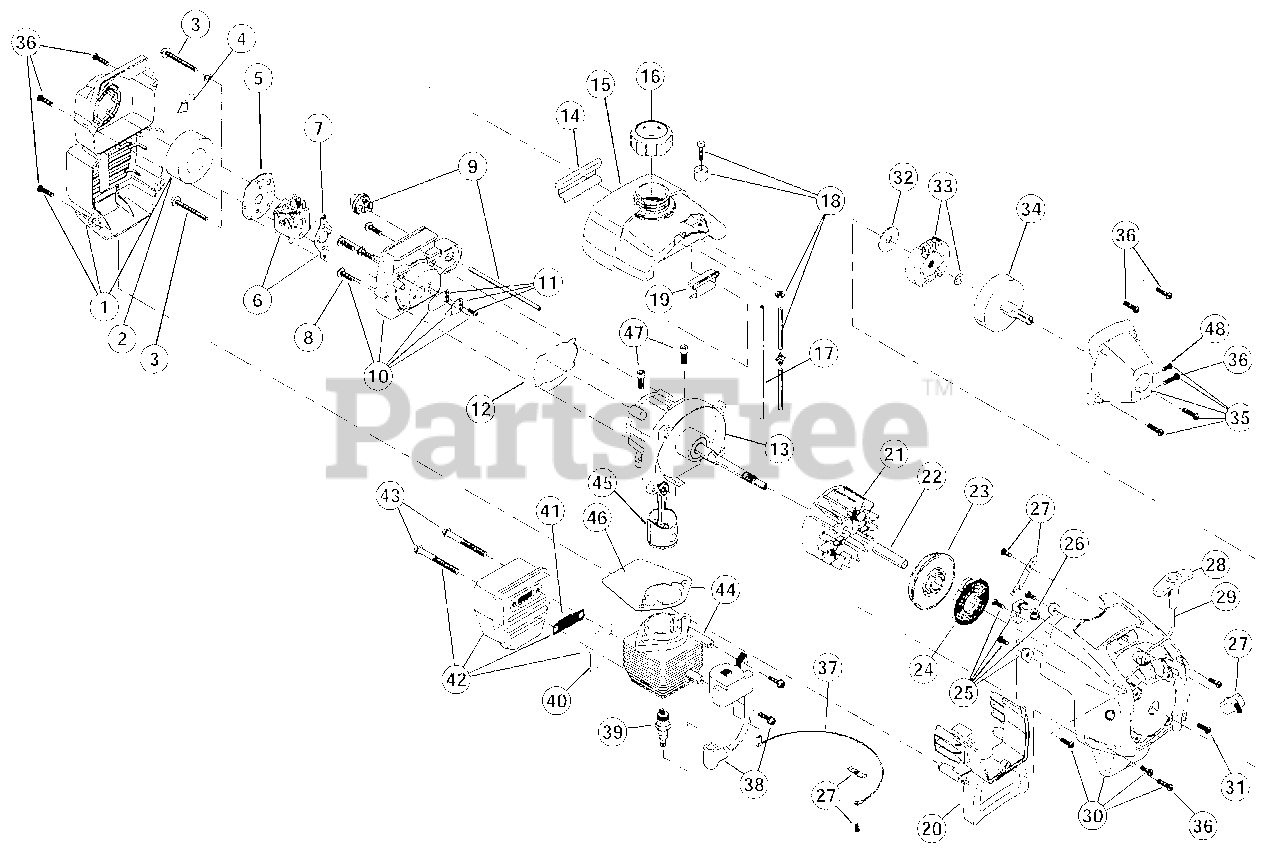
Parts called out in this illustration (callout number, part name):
1	Carburetor/Air Cleaner Cover Assembly
2	Air Cleaner Filter
3	Carburetor Mounting Screws
4	Choke Lever
5	Plate
6	Carburetor Assembly
7	Carburetor Gasket
8	Carb Mount Screw
9	Primer & Hose Assembly
10	Carb Mount Assembly
11	Reed Assembly
12	Carburetor Mount Gasket
13	Crank Case Service Assembly
14	Rear Mounting Pad
15	Fuel Tank Assembly
16	Fuel Cap Assembly
17	Fuel Return Line
18	Fuel Line Assembly
19	Front Mounting Pad
20	Shroud Extension and Stand
21	Flywheel Assembly
23	Recoil Pulley Assembly
24	Recoil Spring
25	Pulley Retainer Assembly
26	Rope Guide
27	Switch Assembly
28	Pull Handle
30	Starter Housing Assembly
31	Housing Screw
32	Clutch Washer
33	Clutch Rotor Assembly
34	Clutch Drum Assembly
35	Clutch Cover Assembly
36	Cover Screws
37	Wire Lead
38	Module Assembly
39	Spark Plug
40	Exhaust Gasket
41	Spark Arrestor
42	Muffler Assembly
43	Muffler Mounting Bolt Assembly
44	Cylinder Assembly
45	Piston and Rod Assembly
46	Cylinder Gasket
47	Cylinder Bolt
48	Anti-Rotation Screw
